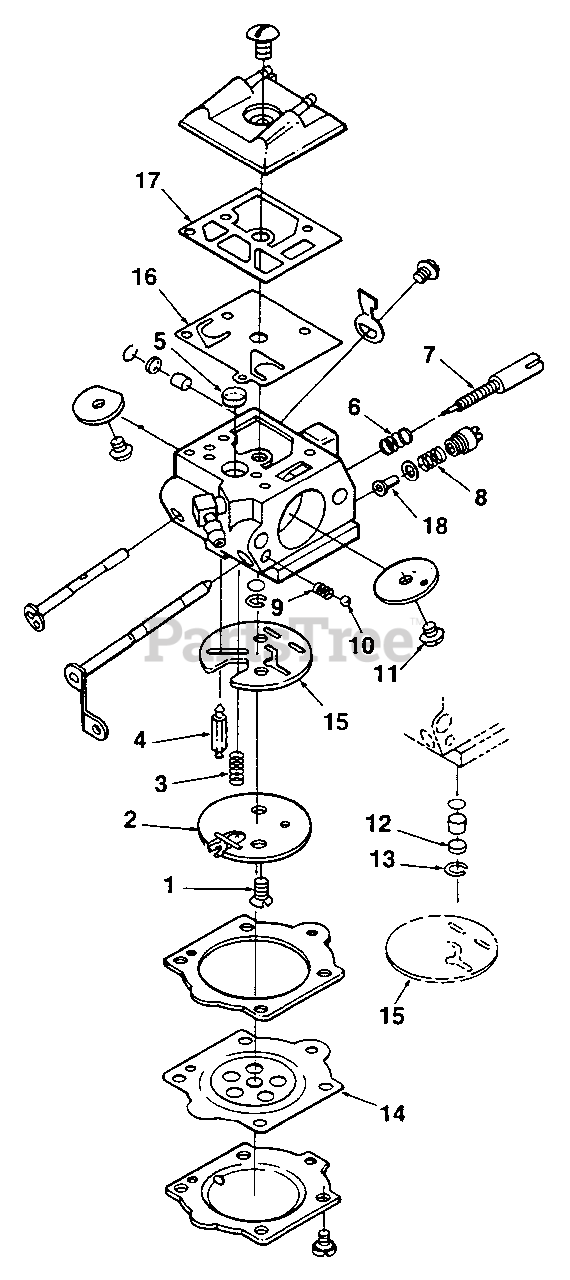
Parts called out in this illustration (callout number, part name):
1	Repair Kit
2	Repair Kit
3	Repair Kit
4	Repair Kit
5	Repair Kit
6	Repair Kit
7	Repair Kit
8	Repair Kit
9	Repair Kit
10	Repair Kit
11	Repair Kit
12	Repair Kit
13	Repair Kit
14	Repair Kit
14	Gasket/Diaphragm Kit
15	Repair Kit
15	Gasket/Diaphragm Kit
16	Repair Kit
16	Gasket/Diaphragm Kit
17	Repair Kit
17	Gasket/Diaphragm Kit
18	Repair Kit
18	Gasket/Diaphragm Kit
